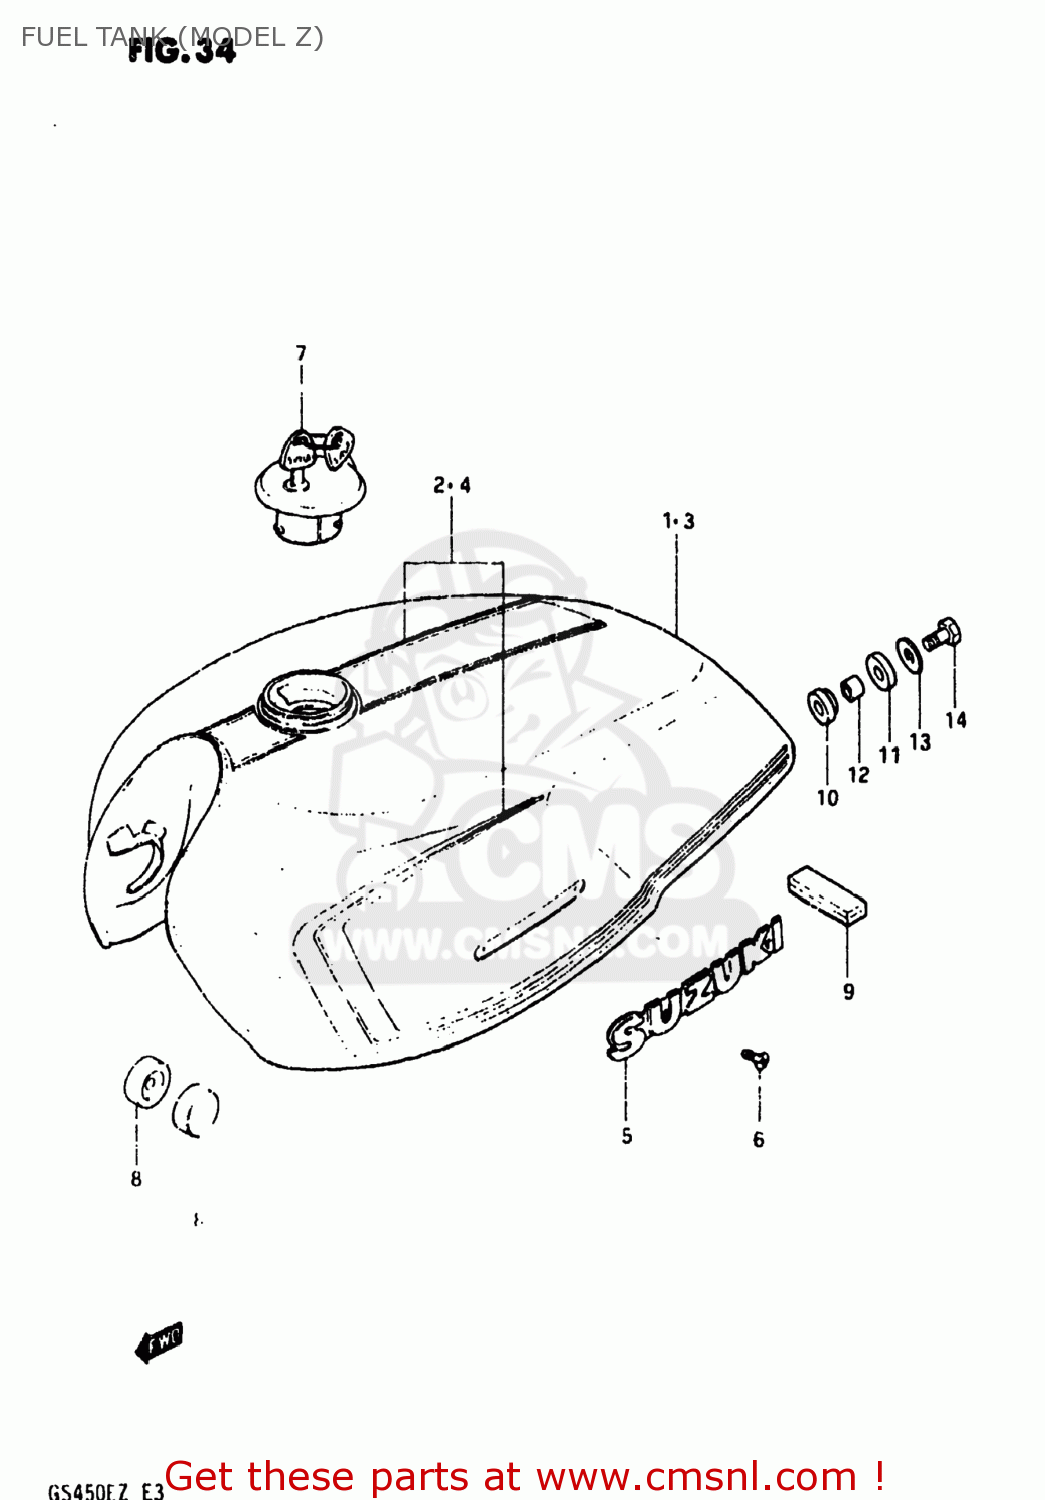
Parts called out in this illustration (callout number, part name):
1	TANK ASSEMBLY,FUEL
2	TAPE SET,FUEL TANK
3	TANK ASSEMBLY,FUEL
4	TAPE SET,FUEL TANK
5	EMBLEM
6	SCREW 3X6
7	CAP SET,FUEL TANK
8	CUSHION
9	CUSHION
10	CUSHION
11	CUSHION
12	SPACER(8.5X12X19)
13	WASHER (8.5X29X1.6)
14	BOLT (8X30)
